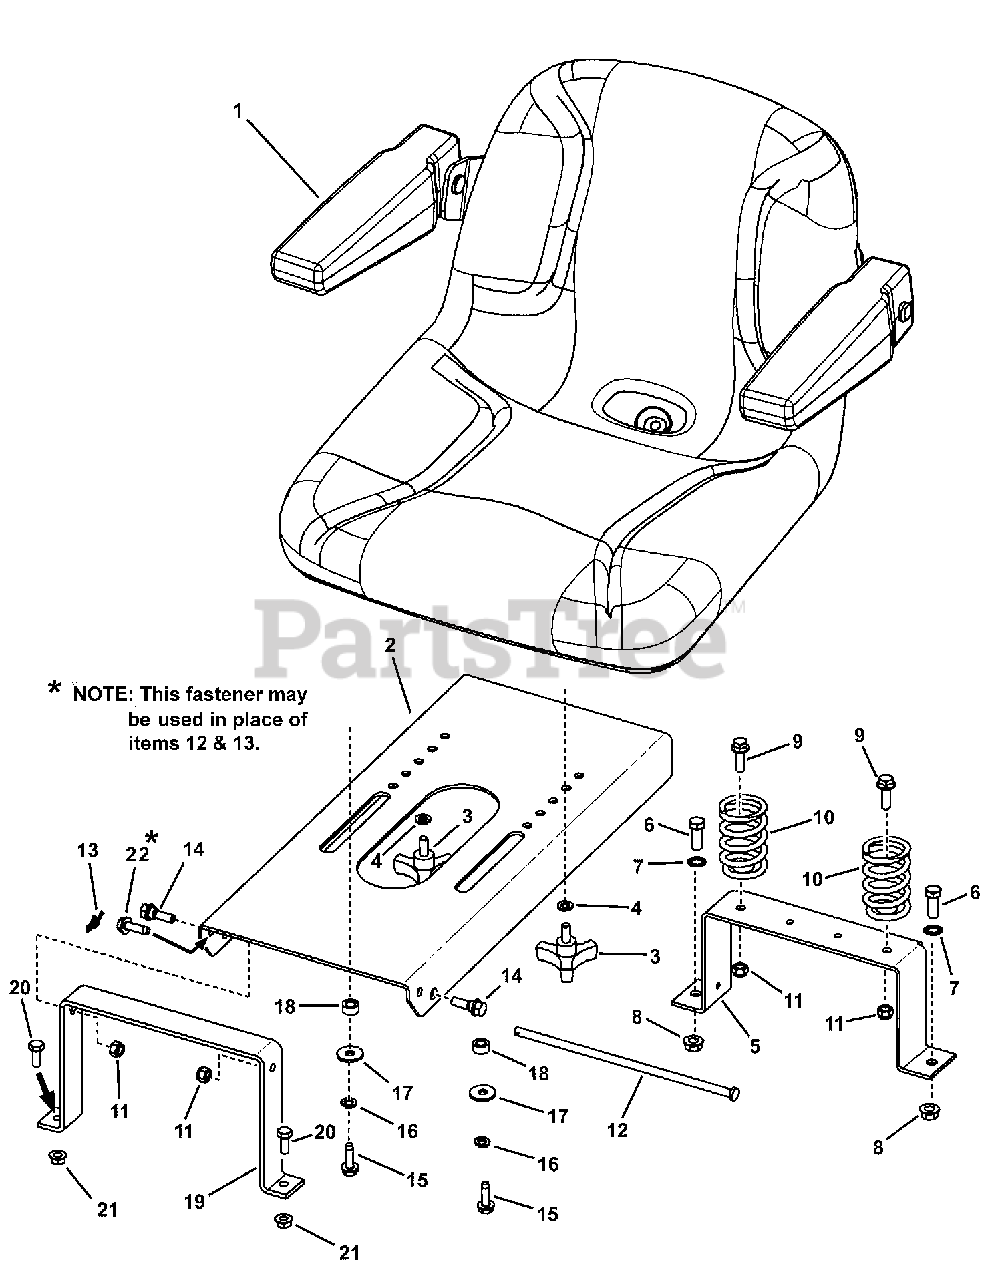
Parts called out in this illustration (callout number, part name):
1	ASSEMBLY, 15" Seat, w/Armrests
2	SEAT PLATE
3	KNOB, Three Prong, 5/16-18 thread
4	WASHER, 5/16" Split Lock
5	BRACKET, Seat Support
6	SCREW, 3/8-16 x 1" Hex Head Cap, GR 5, YZ
7	WASHER, 3/8" Internal Tooth Lock
8	NUT, 3/8-16 Hex Flange Lock
9	BOLT, 5/16-18 x 1" Hex Flange Lock, GR 5, YZ
10	SPRING, Compression- Seat Support
11	NUT, 5/16-18 Hex Nyloc
12	ROD, Seat Hinge
13	COTTER PIN, 3/8" Self-Locking
14	SHOULDER BOLT, 5/16-18 x 1"
15	SCREW, 5/16-18 x 1" Hex Washer Self-Tap, GR 5
16	WASHER, 5/16" Split Lock
17	WASHER, .34 x 1.0 x .09 Flat
18	SPACER, .340 I.D. x .63 O.D. x .310 Thick
19	BRACKET, Lower Seat
20	SCREW, 5/16-18 x 3/4" Hex Head Cap, GR 5, YZ
21	NUT, 5/16-18 Hex Flange Lock, GR 5
22	HWST, 3/8-16 X5/8 (See image note about 12 & 13)
